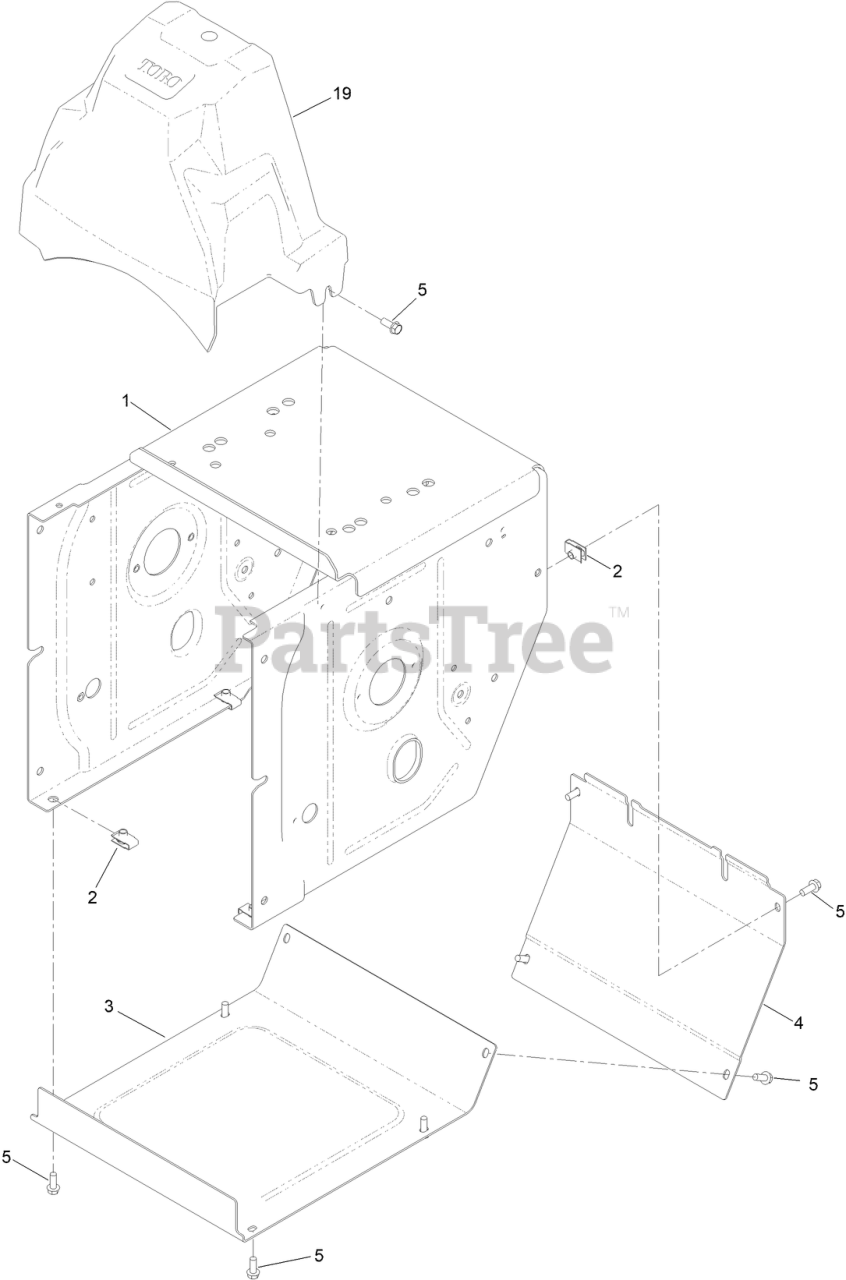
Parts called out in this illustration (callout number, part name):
1	FRAME-TRACTION
3	COVER-BOTTOM
4	COVER-REAR
5	SCREW-HWH
19	BELT COVER, NO LIGHT
